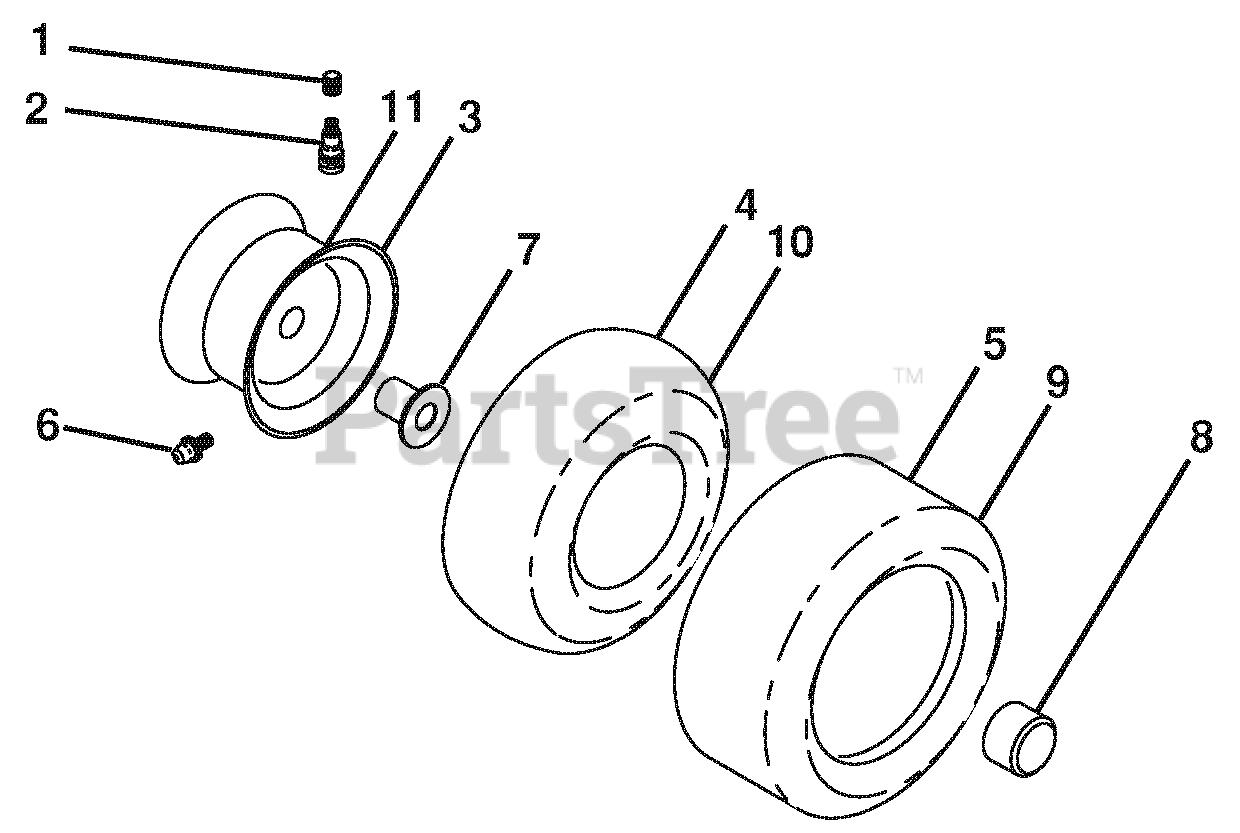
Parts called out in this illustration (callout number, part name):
1	CAP.VALVE.TIRE
2	STEM.VALVE
3	RIM.ASM.6"FRONT
4	TUBE.INNER.FRONT.#35060
5	TIRE.F.TS.15 X 6.0 - 6.SERVICE
6	FITTING.GREASE
7	BEARING.FLANGE
8	CAP.HUB.AXLE.BLK.1.50 X 1.00
9	TIRE.R.TS-LT.18X9.5-8.C.SERV.
10	TUBE.REAR.9.5 X 8.SERVICE
11	RIM.ASM.8"REAR
